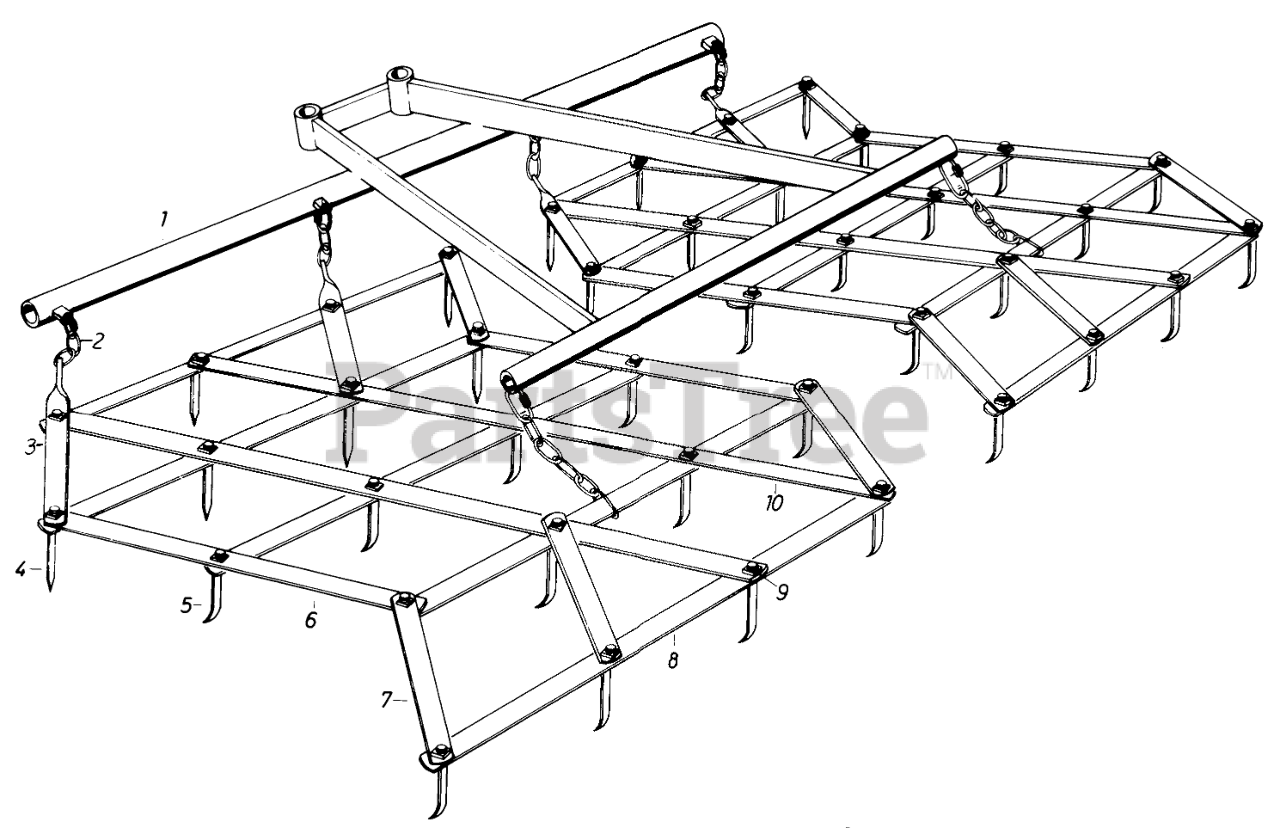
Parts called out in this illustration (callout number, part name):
1	Hitch Assembly (w/Chains)
2	Chain Assembly
5	Curved Tooth
